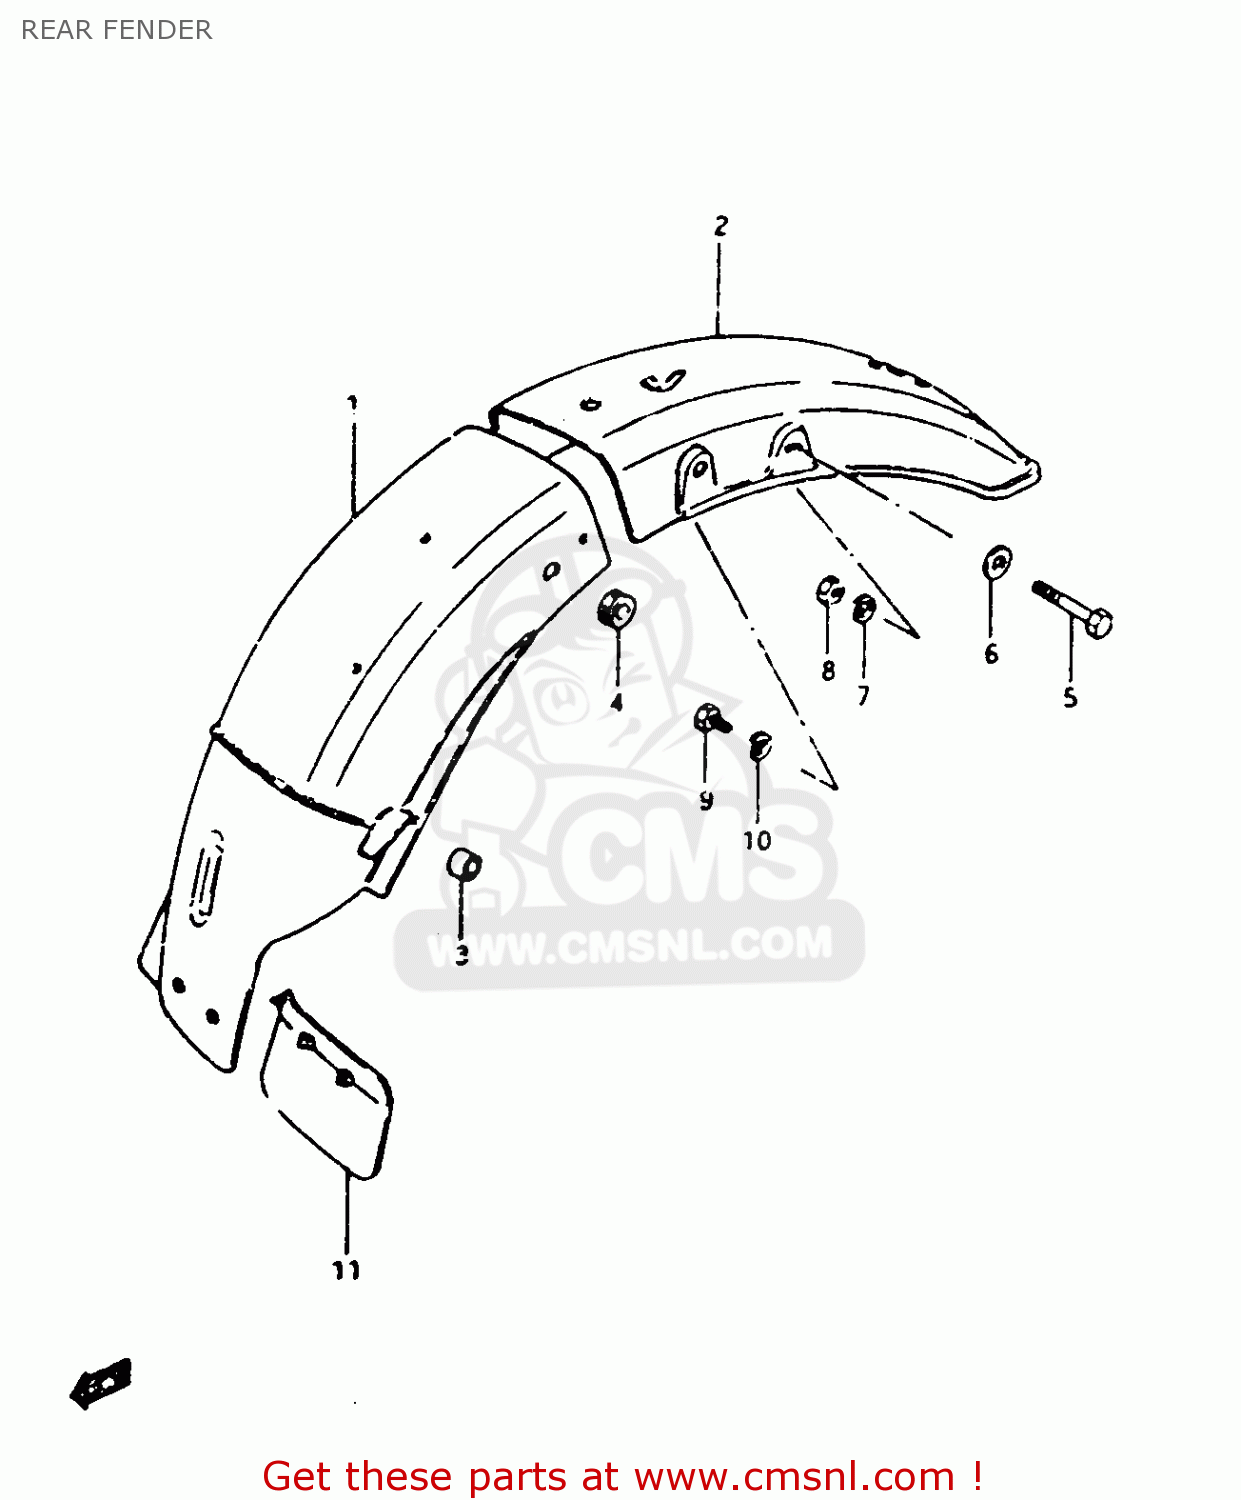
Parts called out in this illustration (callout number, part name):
1	FENDER,REAR
2	FENDER,RR
3	CUSHION
4	CUSHION
5	BOLT
6	WASHER
7	LOCK WASHER
8	NUT
9	BOLT
10	LOCK WASHER
11	GUIDE,RR FENDER MUD
